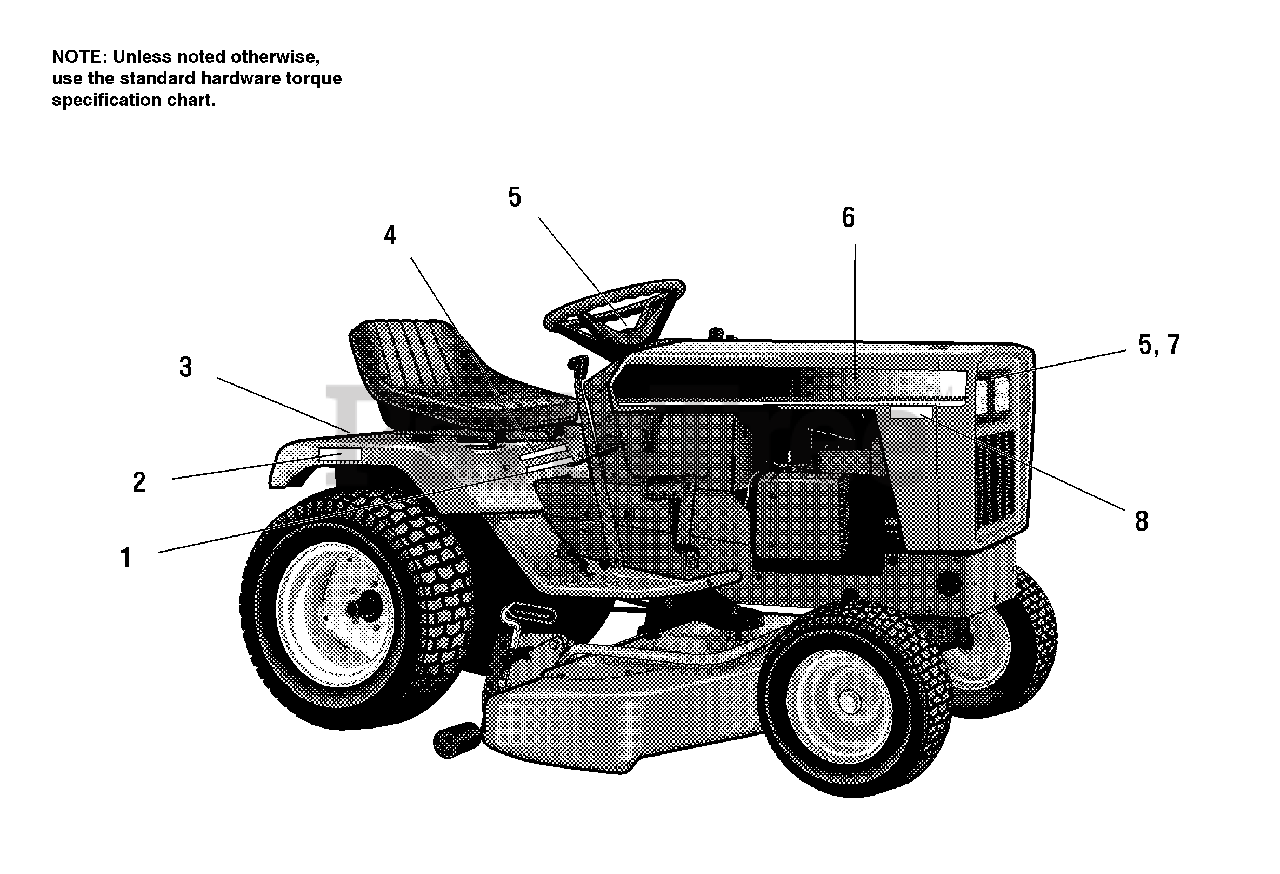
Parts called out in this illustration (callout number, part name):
1	DECAL, 18 V-Twin
2	DECAL, Automatic Controlled Traction
3	DECAL, Simplicity
3	DECAL, Logo, Simplicity
4	DECAL, Sovereign
5	DECAL, Icon
6	DECAL, Hood, LH
6	DECAL, Hood, RH
6	DECAL, Hood, RH Simplicity
6	DECAL, Hood, LH Simplicity
7	DECAL, Logo
7	DECAL, Massey Ferguson
8	DECAL, Model
8	DECAL, Model with P/S
8	DECAL, Power Steering
